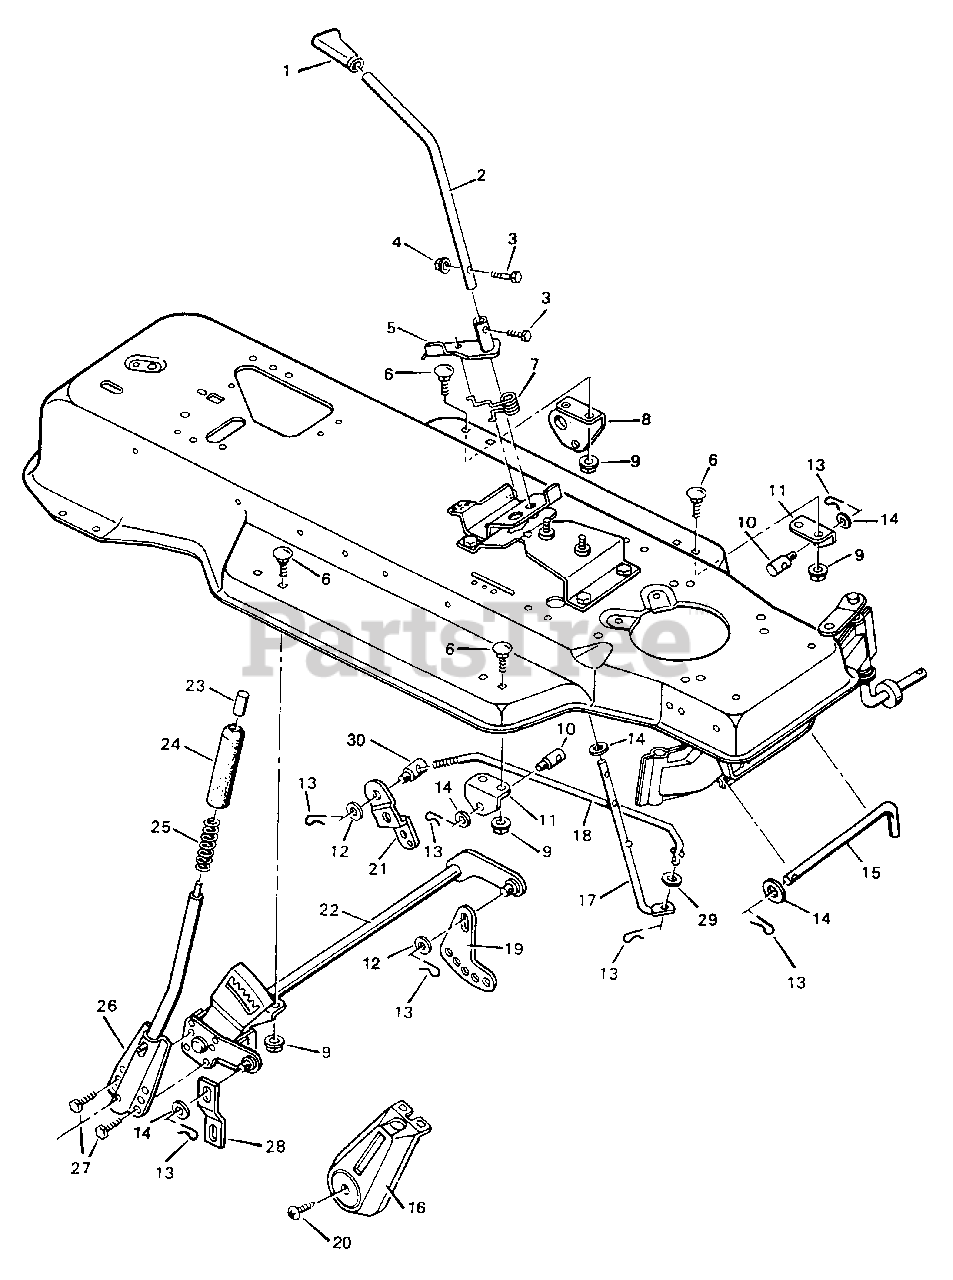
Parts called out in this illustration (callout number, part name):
2	LEVER- Blade control
3	BOLT- Hex
4	NUT- Lock (hex)
5	SWITCH LEVER ASSEMBLY
6	BOLT- Carriage
7	SPRING- Torsion
8	BRACKET- Left rear hanger
9	NUT- Flange
10	NUT- Adjusting
11	BRACKET- Adjusting rod
13	PIN- Hair
15	PIN- Pull
16	COVER- Lift lever
17	LEVER- Lower blade control
18	ROD- Blade control
19	PLATE- Adjuster
21	BRACKET- Pivot
22	LIFTER ASSEMBLY
23	KNOB- Steel
25	SPRING- Compression
26	HANDLE ASSEMBLY
28	LINK- Suspension
29	WASHER
30	NUT- Adjusting
